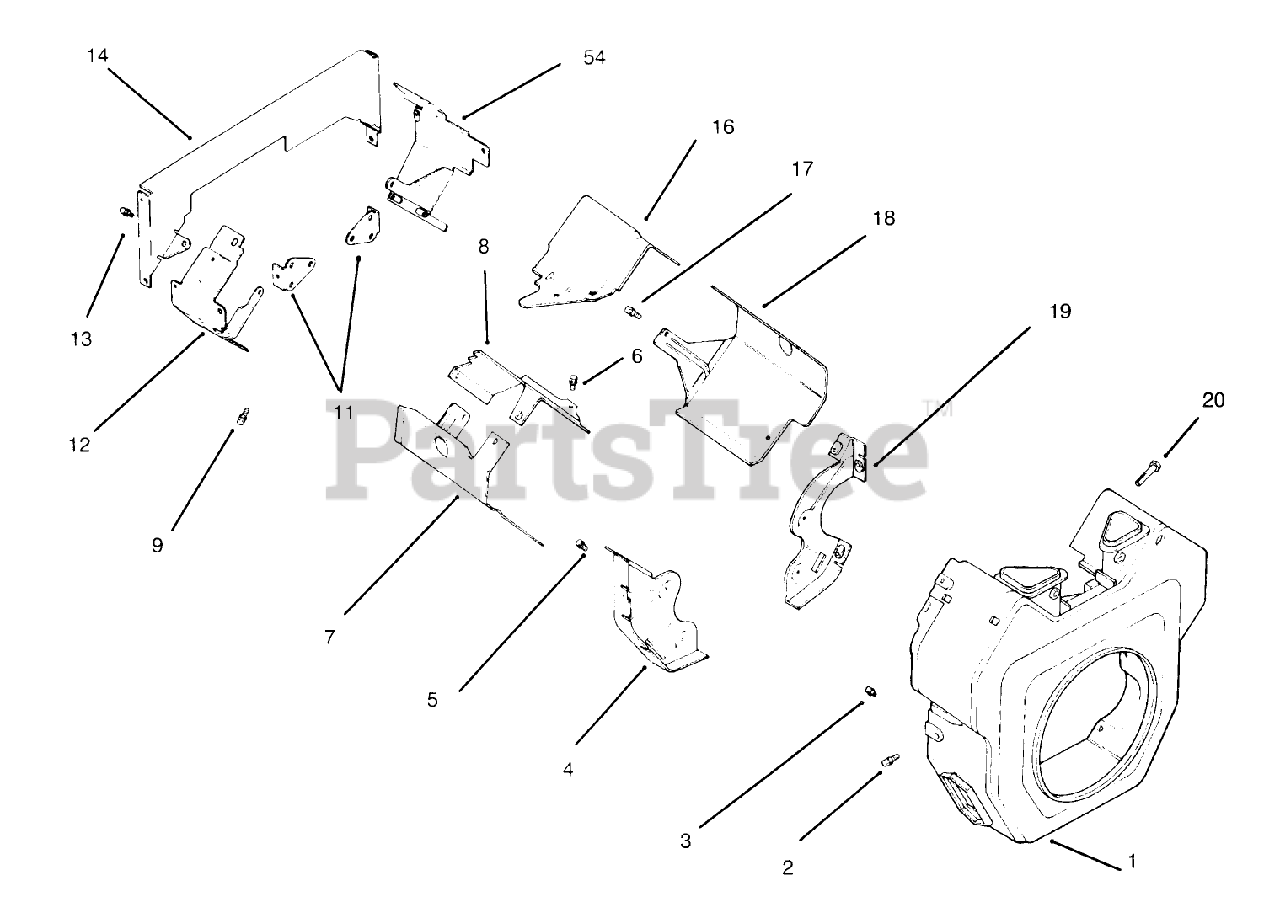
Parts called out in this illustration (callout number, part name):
1	Housing-Blower
2	Screw
3	Screw
4	Plate-Backing #2 Side
5	Screw
6	Screw
7	Baffle-Cylinder, #2
8	Baffle-Valley, #2 side
9	Screw
10	Kit-"Q"Duct (Incl. Ref. #11-15)
11	Bracket-Support
12	Baffle,-Ducted Air #1 side
14	Plat-Ducted Air Backing
15	Baffle-Valley #2 Side
16	Baffle-Valley, #1 Side
17	Screw
18	Baffle, cylinder barrel
19	Plate-Backing #1
